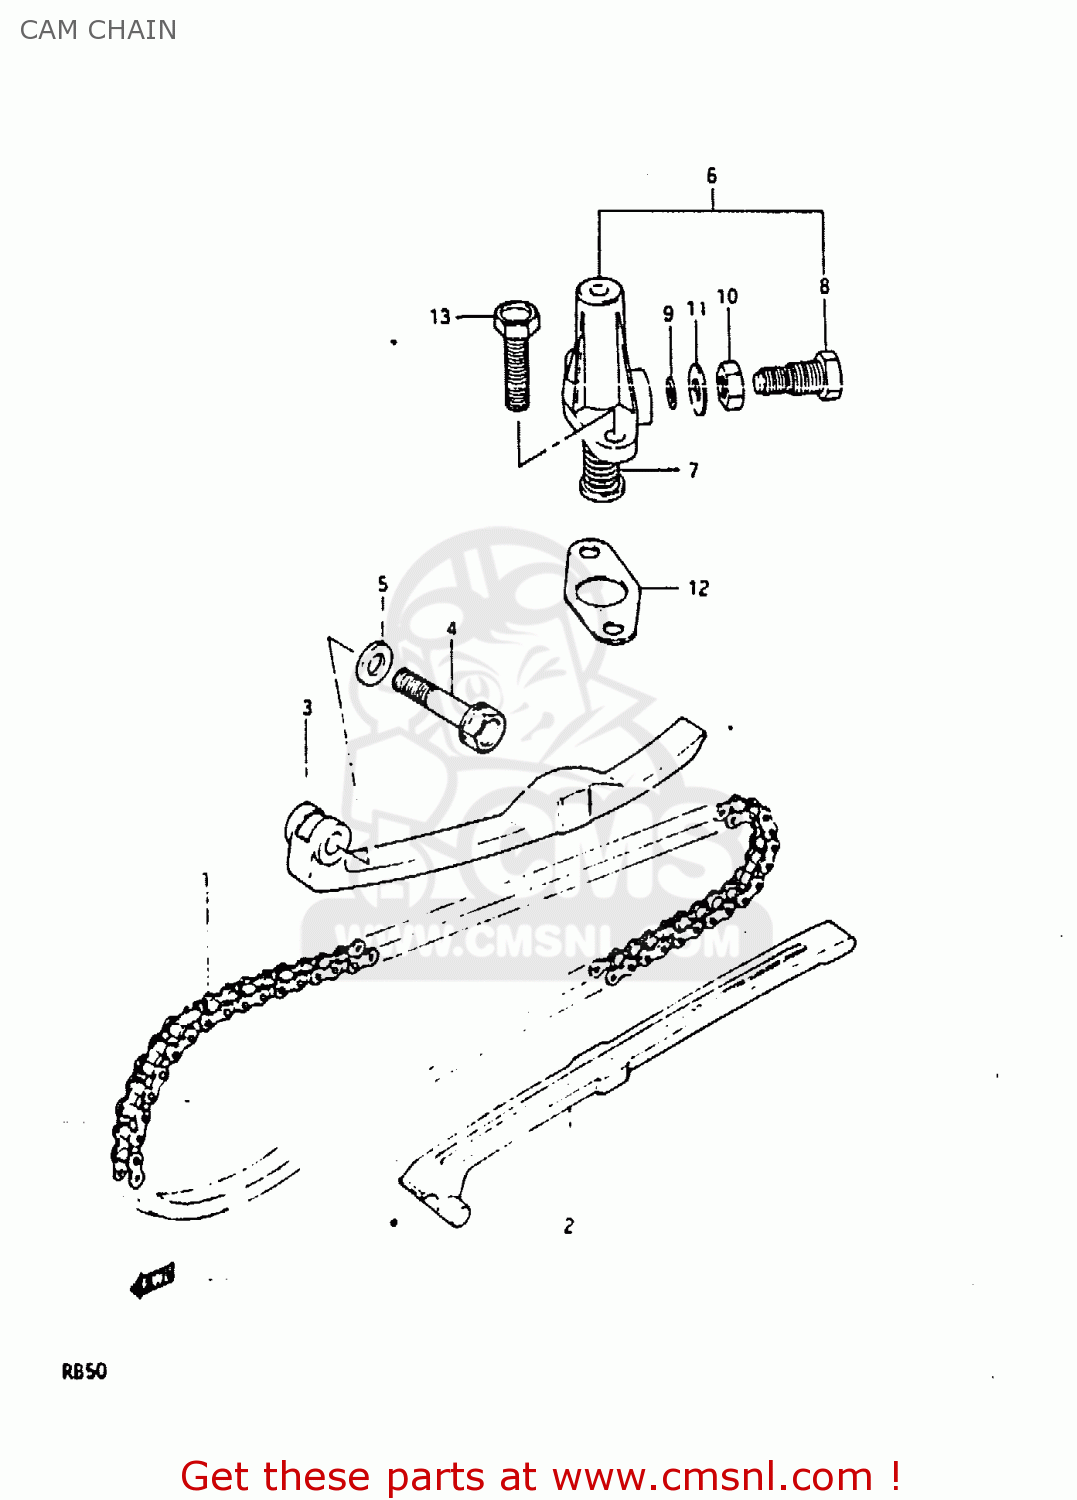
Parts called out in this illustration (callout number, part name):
1	CHAIN,CAMSHAFT DRIVE
2	GUIDE,CAM CHAIN
3	TENSIONER,CAM CHAIN
4	BOLT,CAM CHAIN TENSIONER
5	GASKET(6.2X11X1).2 (NAS)
6	ADJUSTER ASSEMBLY,TENSIONER
7	SPRING
9	O RING(D:1.9,ID:5.7)
10	NUT
11	WASHER
12	GASKET,TENSIONER ADJUSTER (NAS)
13	BOLT(6X20)
